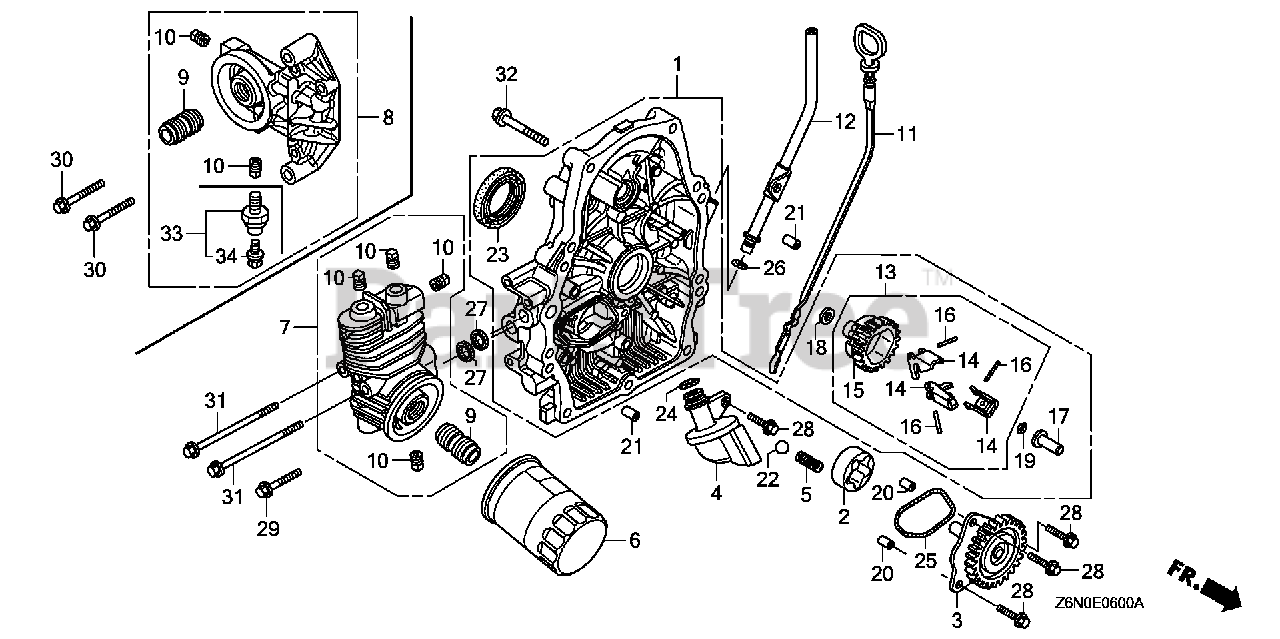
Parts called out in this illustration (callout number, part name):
1	COVER ASSY., CRANKCASE
2	ROTOR, OIL PUMP (OUTER)
3	GEAR, OIL PUMP
4	STRAINER, OIL
5	SPRING, RELIEF VALVE
6	FILTER, OIL (FILTECH TOYO ROKI) (SOLD INDIVIDUALLY)
8	BASE, OIL FILTER
9	HOLDER, OIL FILTER
10	BOLT, SEALING
11	DIPSTICK, OIL
12	PIPE, OIL LEVEL
13	GOVERNOR ASSY.
14	WEIGHT, GOVERNOR
15	HOLDER, GOVERNOR WEIGHT
16	PIN, GOVERNOR WEIGHT
17	SLIDER, GOVERNOR
18	WASHER (6X16)
19	CLIP, GOVERNOR HOLDER
20	PIN, DOWEL (8X10)
21	PIN, DOWEL (8X14)
22	BALL, STEEL (#15) (15/32)
23	OIL SEAL (38X58X9)
24	O-RING (14.8X2.4)
25	O-RING, OIL PUMP
26	O-RING (8.8X1.9)
27	GASKET, OIL PASSAGE
28	BOLT, FLANGE (6X20)
29	BOLT, FLANGE (6X28)
30	BOLT, FLANGE (6X35)
32	BOLT, FLANGE (8X45)
33	SWITCH, OIL PRESSURE
34	SCREW-WASHER (4X8)
